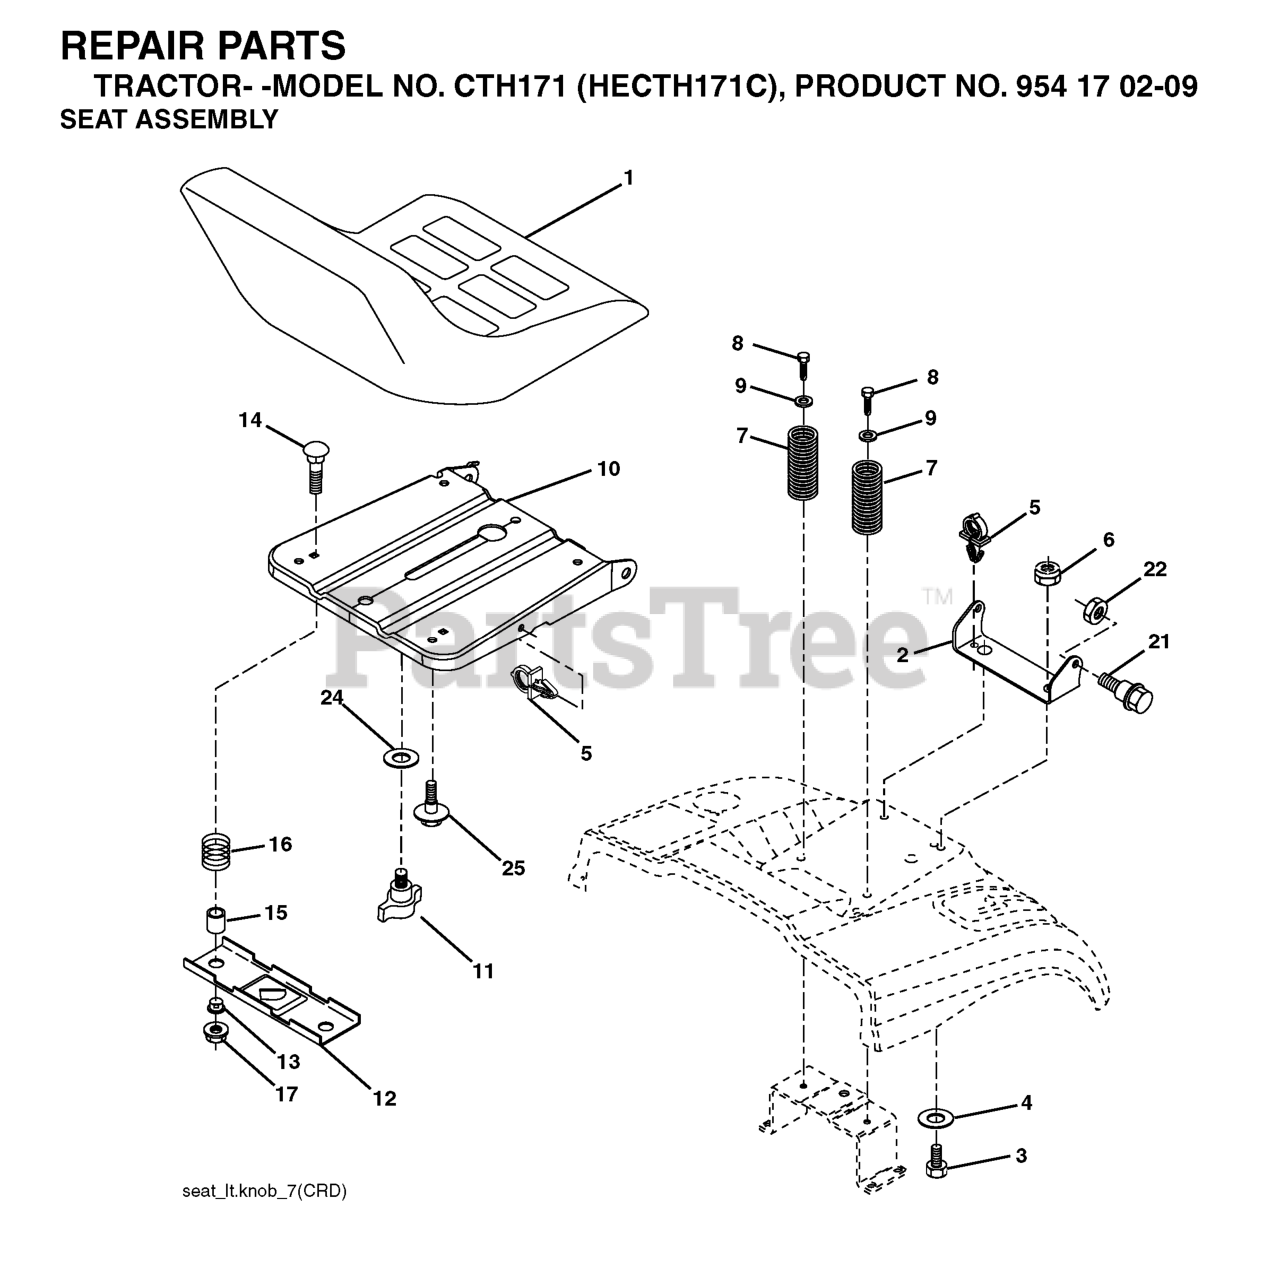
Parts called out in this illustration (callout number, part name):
1	SEAT
2	SEAT PIVOT BRKT
3	BOLT, HEX 3/8-16X1
6	NUT
7	SPRING COMPRESSION
8	SCREW 3/8-16X1
9	WASHER
10	PAN SEAT
11	KNOB.SEAT.ADJ.WINGNUT
12	BRKT SWITCH
14	BOLT.ROUND.HEAD.SQUARE.NECK
15	SPACER SPLIT
16	SPRING COMPRESSED
17	NUT T
21	BOLT.SHOULDER.5/16-18
22	NUT.71038.31-18.HEX.NYLOCK
25	BOLT,SHOULD
